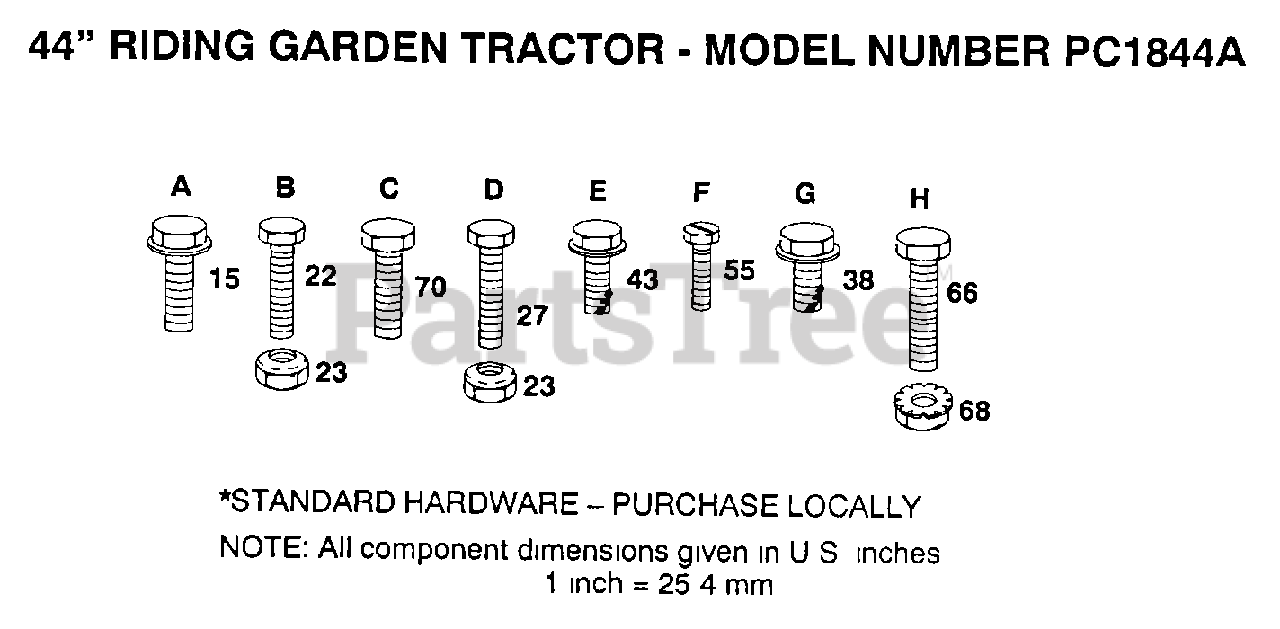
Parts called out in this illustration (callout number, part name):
15	SCREW SPECIAL
22	SCREW
27	BOLT
38	SCREW LT
43	SCREW LT
66	BOLT
68	NUT
70	SCREW
